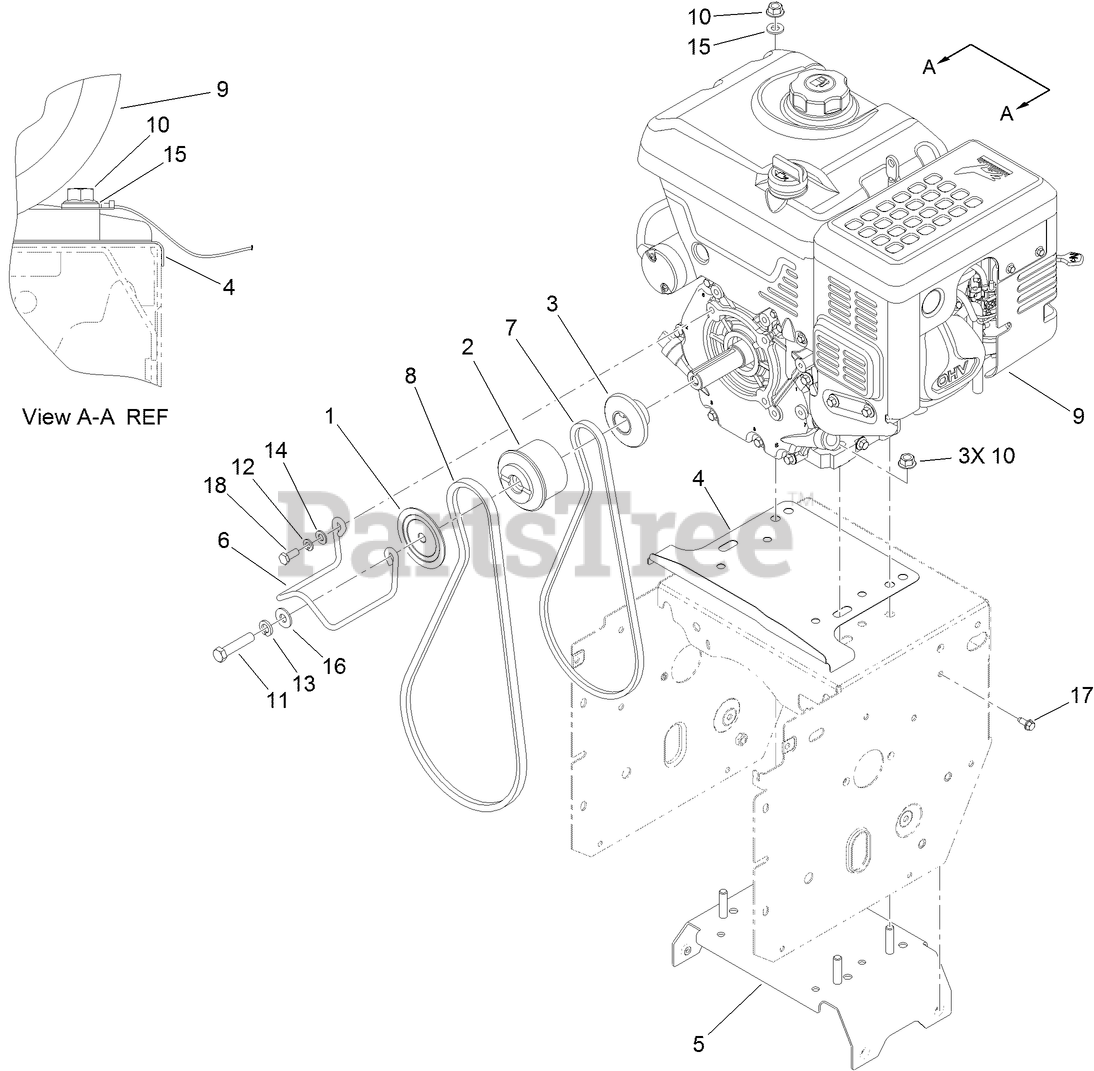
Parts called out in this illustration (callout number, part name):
1	SHEAVE-HALF, IMPELLER
2	PULLEY-ENGINE, CENTER
3	SHEAVE-HALF, TRACTION
4	SHIELD-DRIVE
5	FRAME BRACE ASM
7	BELT-V
8	BELT-V
9	ENGINE-180FDS-1
10	NUT-FLANGE
11	SCREW-HH
12	WASHER-LOCK
13	WASHER-LOCK
14	WASHER-PLAIN
15	WASHER-FLAT
16	WASHER-FLAT
17	SCREW-HWH
18	SCREW-HH
